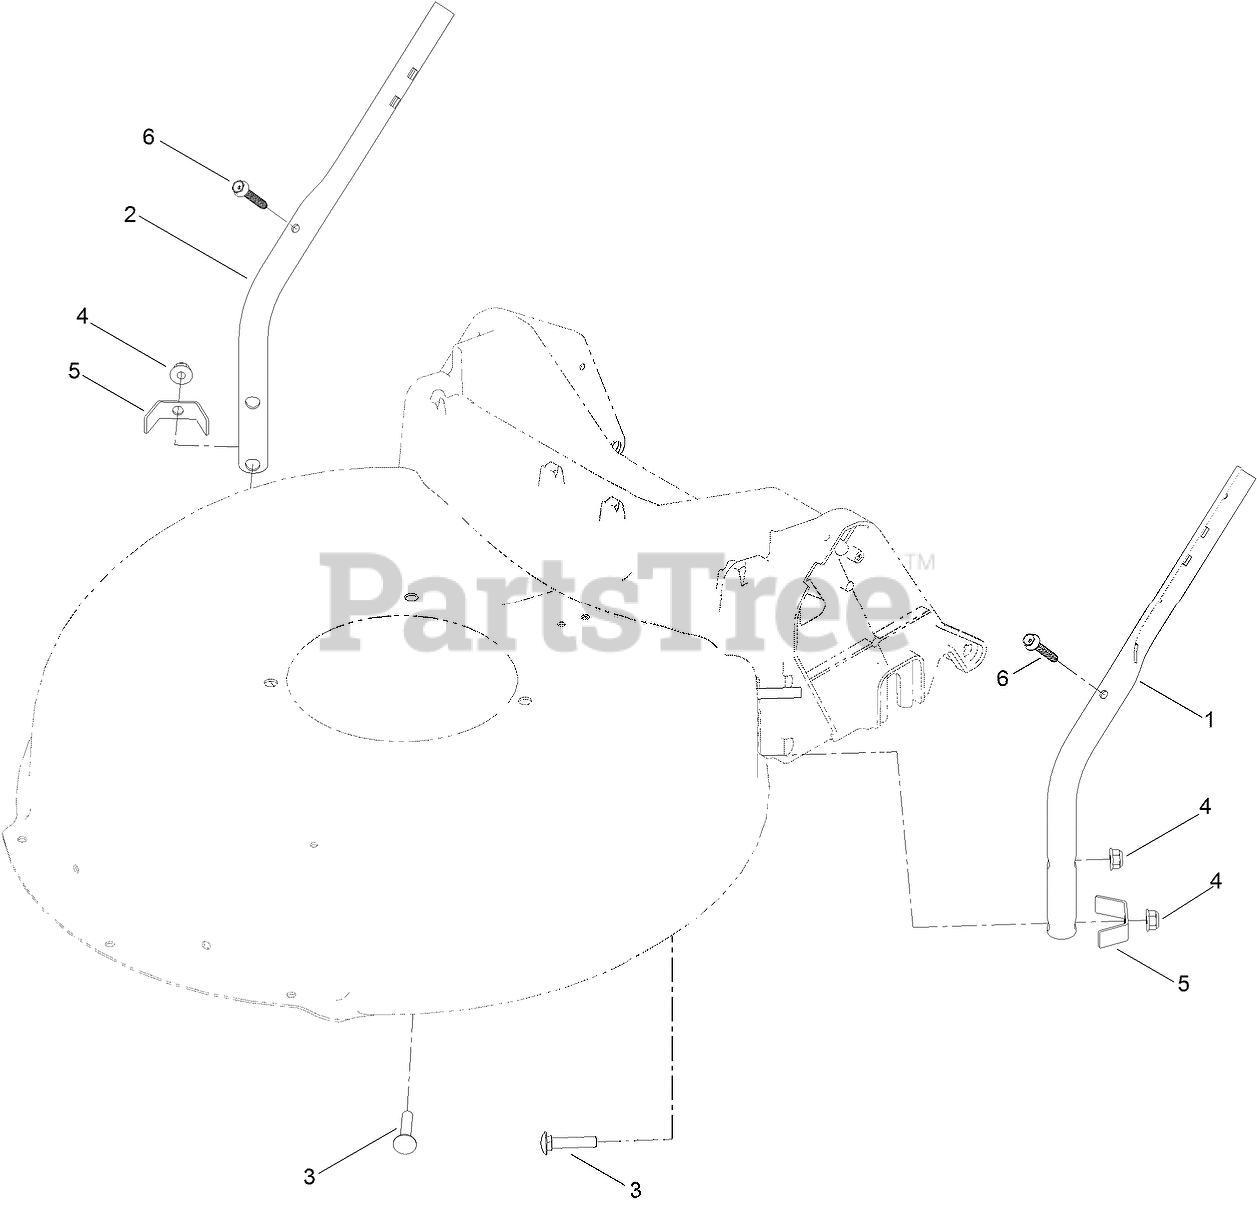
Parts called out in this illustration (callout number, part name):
1	HANDLE-LOWER, LH
2	HANDLE-LOWER, RH
3	BOLT-CARR
4	NUT-FLANGE, NI
5	BRACKET-CHUTE
6	SCREW-FLANGE, SERRATED
